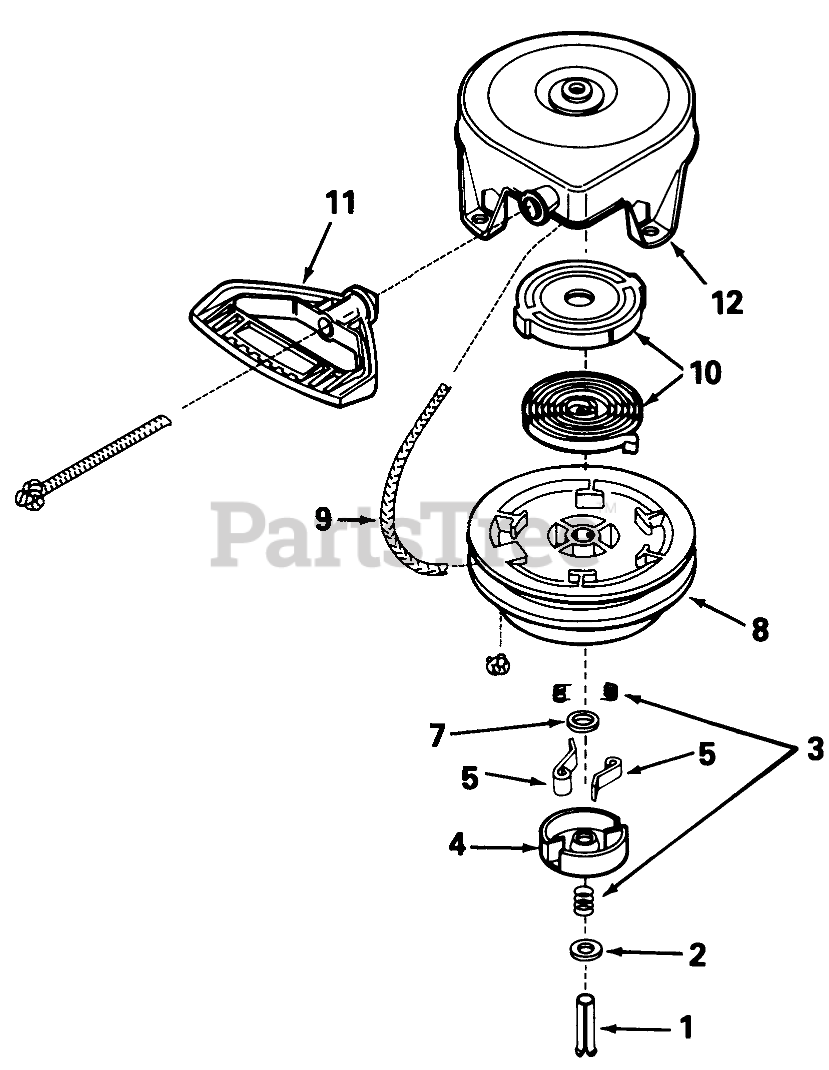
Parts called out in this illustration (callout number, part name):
1	Pin-Spring (Incl. Ref. #7)
3	Spring Assembly
4	Retainer
5	Dog-Starter
9	Rope-Starter
10	Spring & Keeper Assy.
11	Handle-Starter, Mitten Grip
12	Housing Assy., Starter
